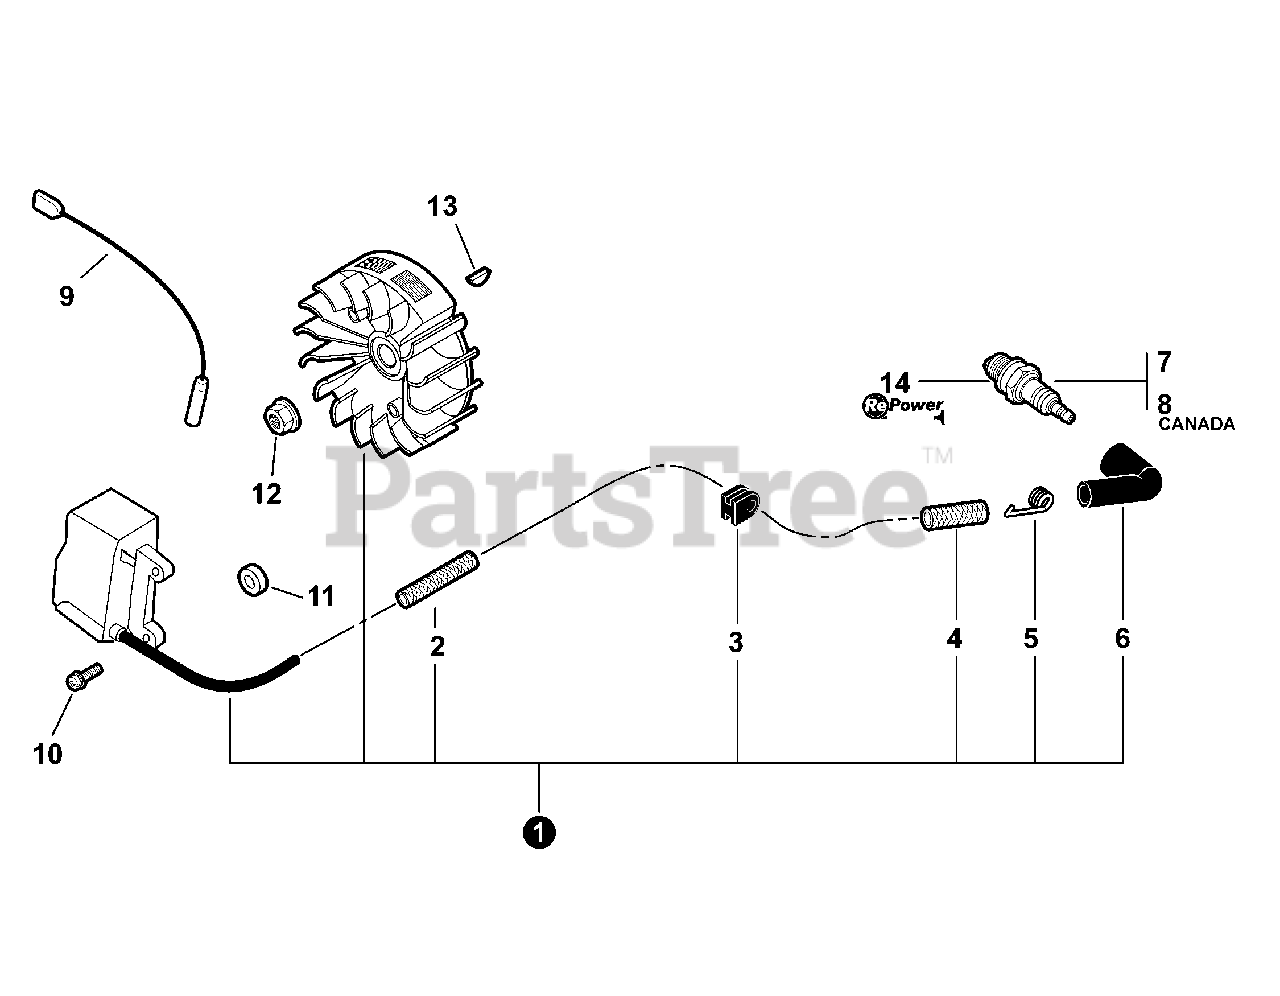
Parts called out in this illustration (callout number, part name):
1	IGNITION KIT
2	TUBE, INSULATOR
4	TUBE, INSULATOR
5	TERMINAL, SPARK PLUG
6	CAP, SPARK PLUG
7	SPARK PLUG - BPM8Y
8	SPARK PLUG - BPMR8Y
9	LEAD - IGNITION
10	SCREW 5×22
11	WASHER 5.2×12×3
12	NUT, FLANGE M8
13	KEY, WOODRUFF
14	TUNE-UP KIT - REPOWER
